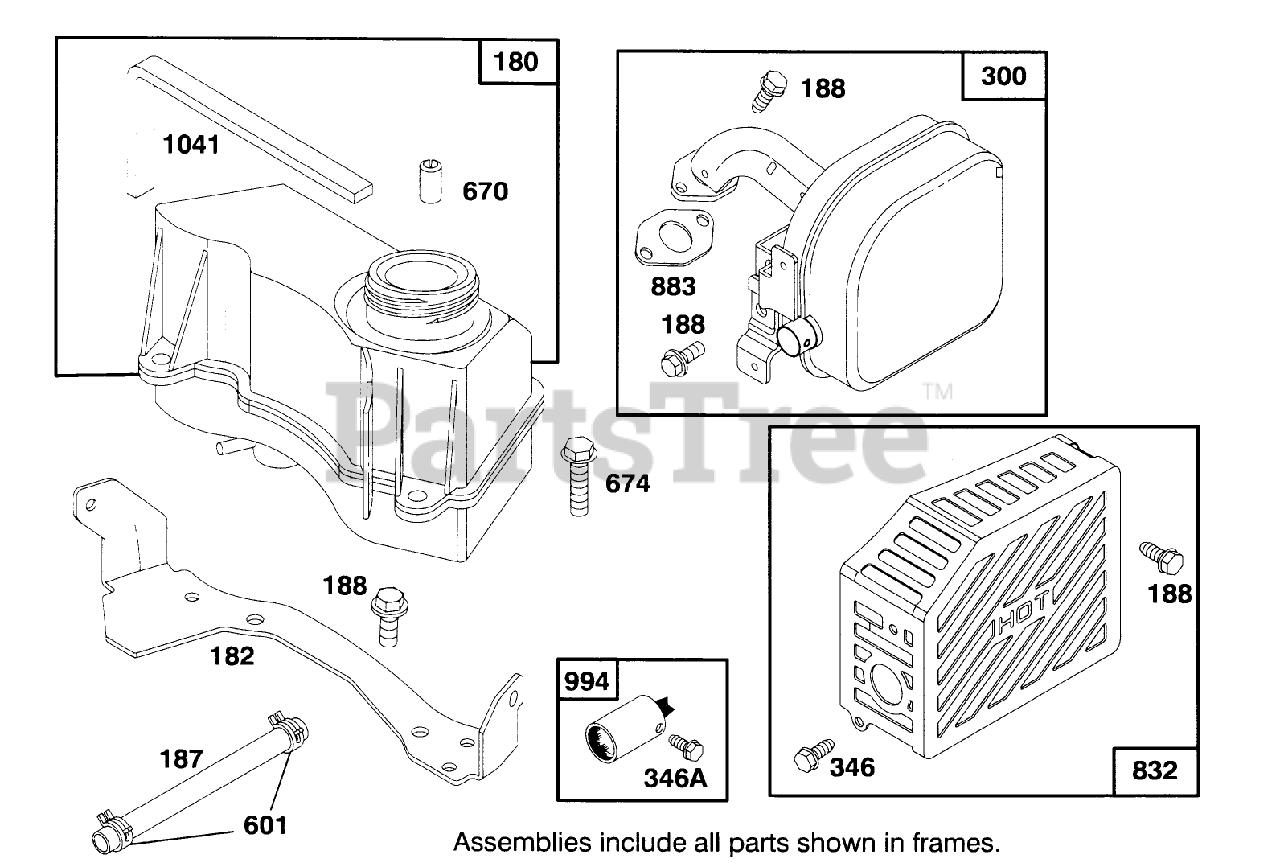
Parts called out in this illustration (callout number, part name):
180	TANK ASSY - FUEL
300	MUFFLER - EXHAUST
601	CLAMP - CL PIPE
670	SPACER
674	SCREW - HEX HEAD
